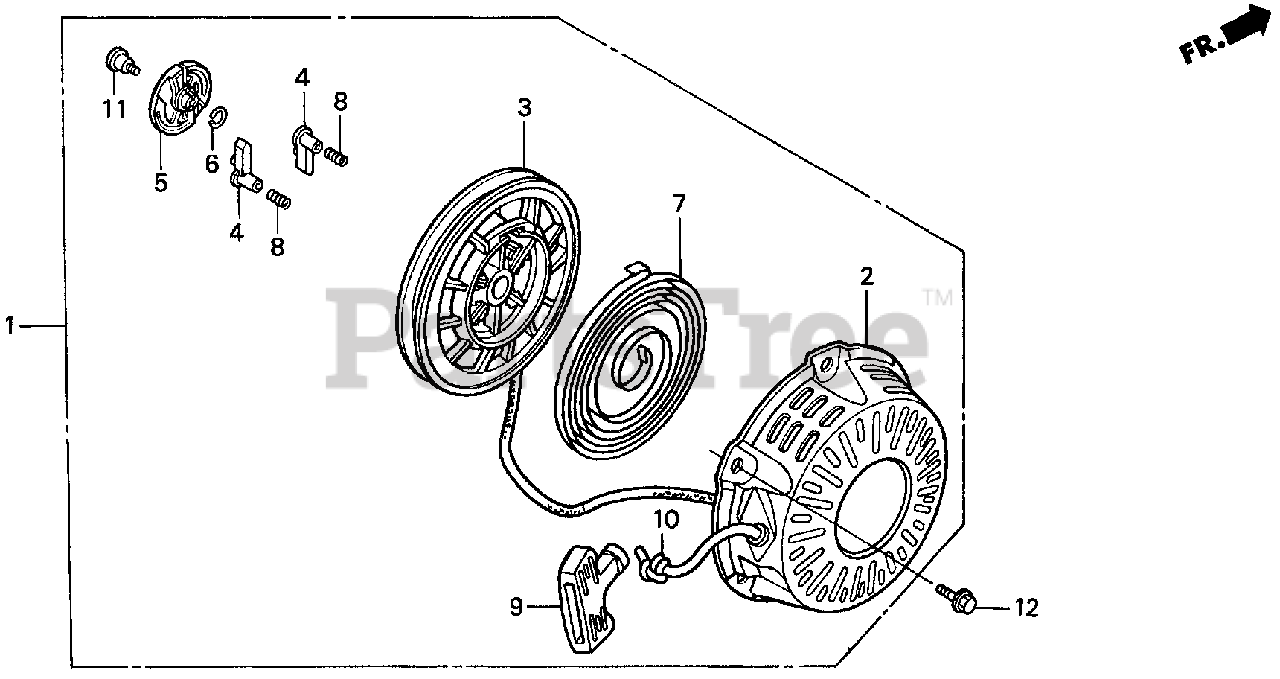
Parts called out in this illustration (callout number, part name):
1	STARTER ASSY., RECOIL *NH1* (BLACK)
2	CASE, RECOIL STARTER *NH1* (BLACK)
3	REEL, RECOIL STARTER
4	RATCHET, STARTER
5	GUIDE, RATCHET
6	SPRING, FRICTION
7	SPRING, RECOIL STARTER
8	SPRING, RETURN
9	KNOB, RECOIL STARTER
10	ROPE, RECOIL STARTER (#5X55")
11	SCREW, SETTING
12	BOLT, FLANGE (6X10)
